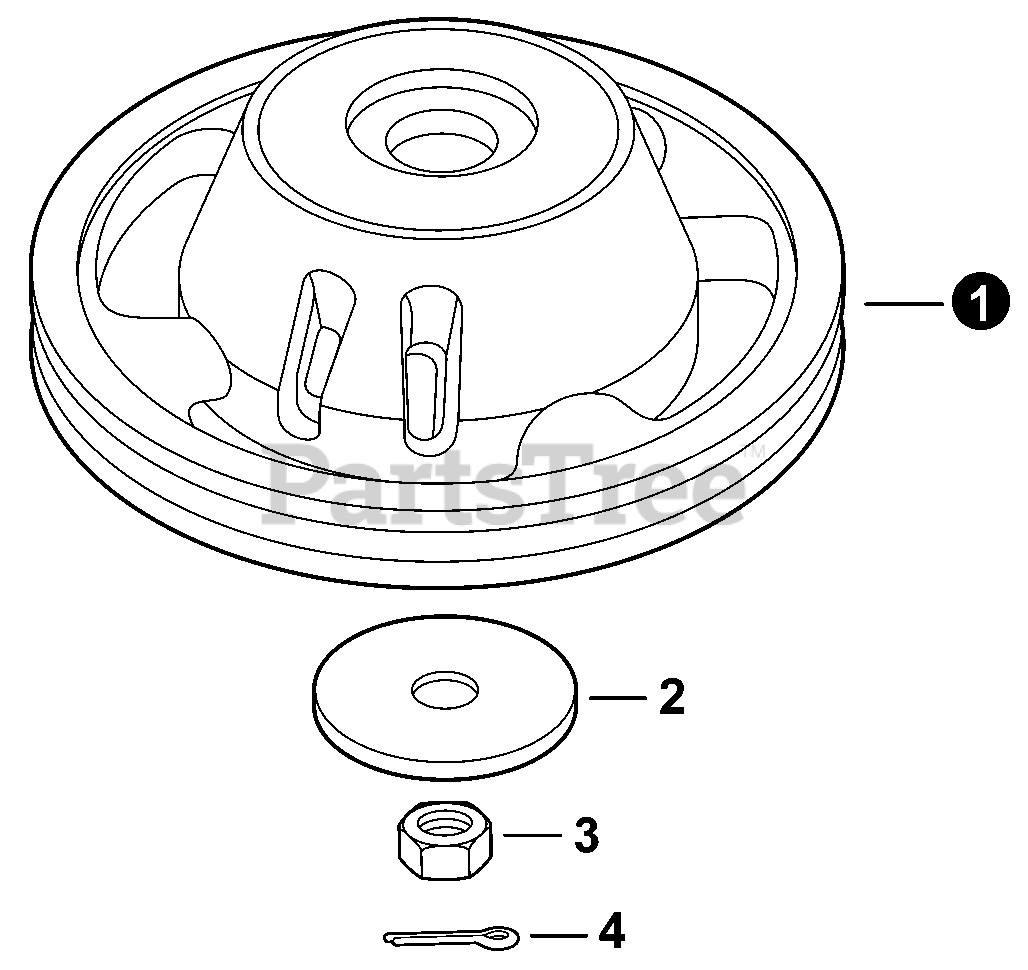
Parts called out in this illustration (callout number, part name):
1	FIXED LINE HEAD, HEAVY DUTY
2	WASHER 10
4	PIN, COTTER 2x22
